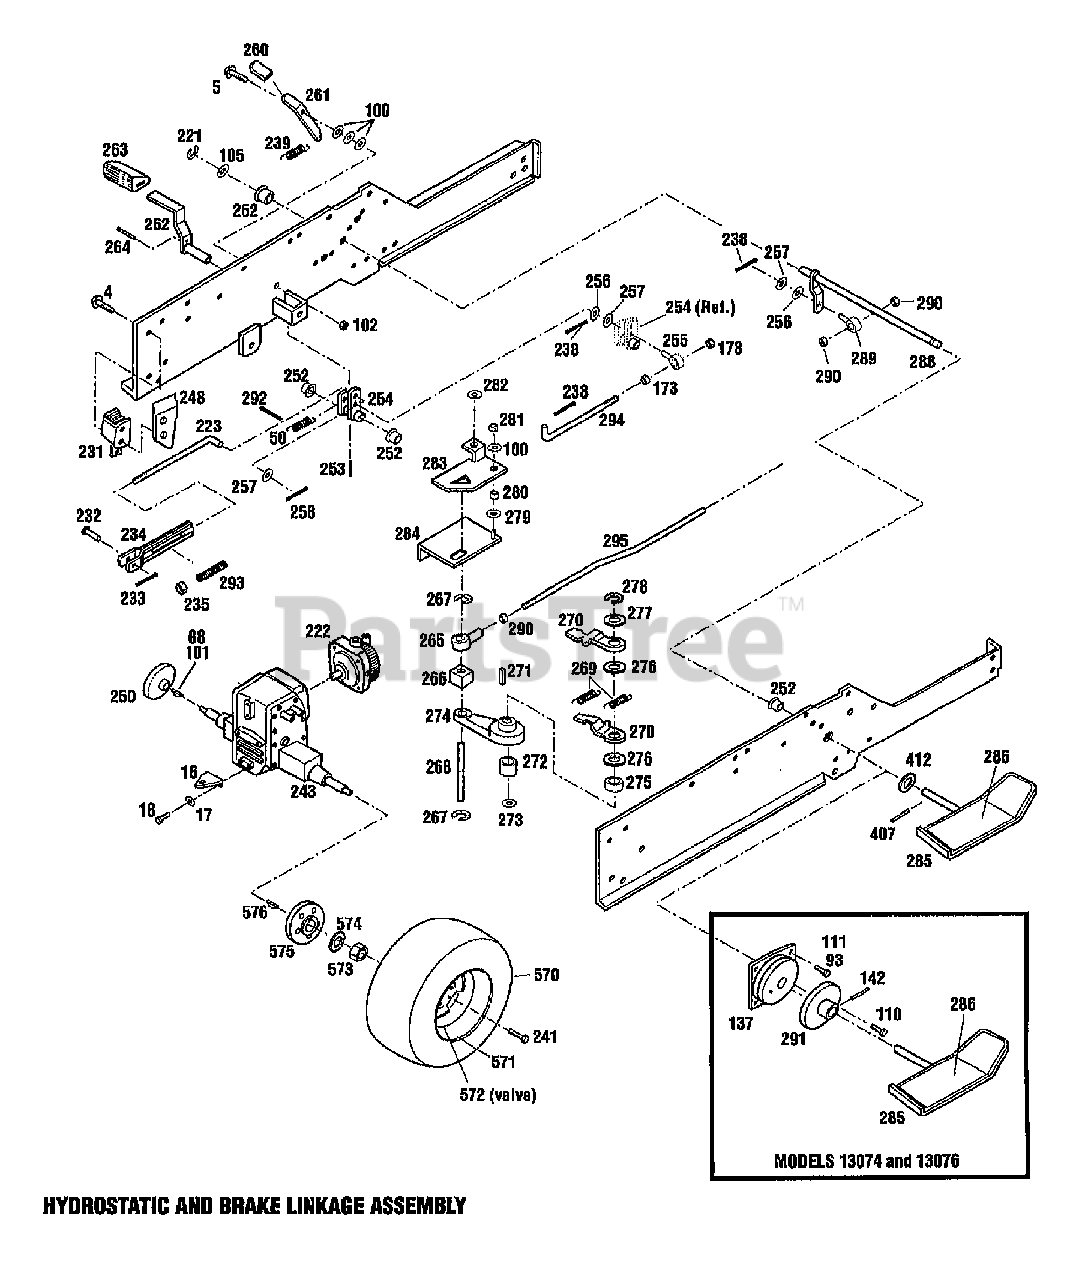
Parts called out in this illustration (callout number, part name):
5	SCR-HFLK 3/8-16X1.00 ZP
16	HITCH-DRAWBAR
17	WASHER-LK .5
18	SCR-HH 1/2-13X1.25 G5 ZP
68	KEY-WOODRUFF .188X.75
93	NUT W/LKWASHER 10-24 ZP
100	WASHER-FLAT 3/8 SAE
101	KEY-WOODRUFF .25X.75
102	NUT-LOCK 3/8-16
105	WASHER-1.115X.637X.06
111	SCR-SEMS MACH
137	CLUTCH
142	PIN-ROLL
173	NUT-HEX 5/16-18 ZP
221	RING-RETAIN .625 ID
222	PUMP-HYDRO
223	ROD-BRAKE
231	ASSY BRAKE-CYLINDER
232	PIN-CLEVIS .25X.62
233	PIN-COTTER
234	SPRING-YOKE ASSM
235	NUT-SPECIAL
238	PIN-COTTER .09X.75 ZP
239	SPRING
241	BOLT-HUB
243	ASSM-TRANSAXLE
248	BRKT-TRANS SUPPORT
250	BRAKE-DISC
250	DISC-BRAKE
252	BEARING-FLANGE
253	PIN-DRIVE .187X1.0
255	SWIVEL
256	WASHER-.632X.39X.0329
257	WASHER-FLAT 5/16 SAE
258	PIN-COTTER .125 X .75 ZP
262	PEDAL-BRAKE
263	FOOT REST
264	PIN-ROLL .188X.75
265	ROD-END
267	RING-RET.EXT .437 ID
268	PIN-CONTROL
269	SPRING
271	KEY-WOODRUFF 1/8 X 5/8
272	WASHER-1.06X.531X.1 ZP
273	NUT-H/LK 1/2-13
274	ARM-SPEED CONTROL
275	BEARING
276	WASHER-THRUST
277	WASHER
278	RING-RET
279	WASHER-1.75X.39X.059
280	SPACER-.625X.4X.2
281	NUT-HEX/JAM 3/8-16 ZP
281	NUT-H/LK 3/8-16
282	WASHER-.75X.312X.065 ZP
283	PLATE-NEUTRAL
284	PLATE-NEUTRAL
285	ASSM-PEDAL HYDRO
286	PAD-FOOT PEDAL
288	SHAFT-SPEED CONTROL
289	SWIVEL
290	NUT-HEX/JAM 7/16-20
291	ASSM-CONTROL DISC
292	PIN-COTTER .120X1.00 ZP
293	SPRING-COMPRESSION
294	ROD-BRAKE CONTROL
295	ROD-SPEED CONTROL
571	RIM-WHEEL REAR
572	STEM-VALVE
573	NUT-H/LK 3/4-10
574	SPACER-1.812X.765X.179
575	HUB-WHEEL
576	KEY-WOODRUFF .312X1.12
